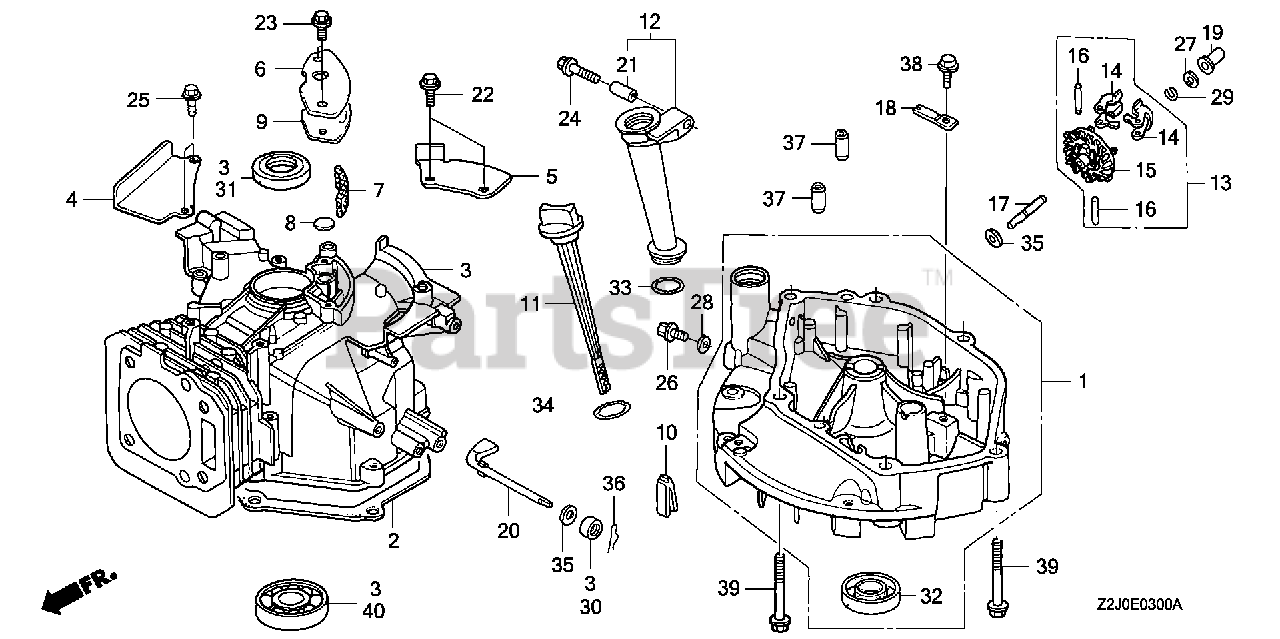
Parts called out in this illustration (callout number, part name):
1	PAN ASSY., OIL
2	GASKET, OIL PAN
3	CYLINDER ASSY.
4	PLATE, GUIDE
5	PLATE A, GUIDE
6	COVER, BREATHER
7	FILTER, BREATHER
8	VALVE, BREATHER
9	GASKET, BREATHER COVER
10	RUBBER, OIL RETURN
11	GAUGE, OIL LEVEL
12	EXTENSION, OIL FILLER
13	GOVERNOR ASSY.
14	WEIGHT, GOVERNOR
15	HOLDER, GOVERNOR WEIGHT
16	PIN, GOVERNOR WEIGHT
17	SHAFT, GOVERNOR HOLDER
18	PLATE, GOVERNOR SHAFT HOLDER
19	SLIDER, GOVERNOR
20	SHAFT, GOVERNOR ARM
21	COLLAR, EXTENSION
22	BOLT, FLANGE (6X12) (CT200)
23	BOLT, FLANGE (6X14) (CT200)
24	BOLT, FLANGE (6X32)
25	BOLT, FLANGE (6X20) (CT200)
26	BOLT, DRAIN PLUG
27	WASHER, THRUST (6MM)
28	WASHER, DRAIN PLUG (10.2MM)
29	CLIP, GOVERNOR HOLDER
30	OIL SEAL (6X11X4) (ARAI)
31	OIL SEAL (25X38X7) (ARAI)
32	OIL SEAL (25.4X40X7)
33	O-RING (22.1X2.2)
34	O-RING (26X2.7)
35	WASHER, PLAIN (6MM)
36	PIN, LOCK (8MM)
37	PIN, DOWEL (8X14)
38	BOLT, FLANGE (6X12)
39	BOLT, FLANGE (8X50)
40	BEARING, RADIAL BALL (6205)
